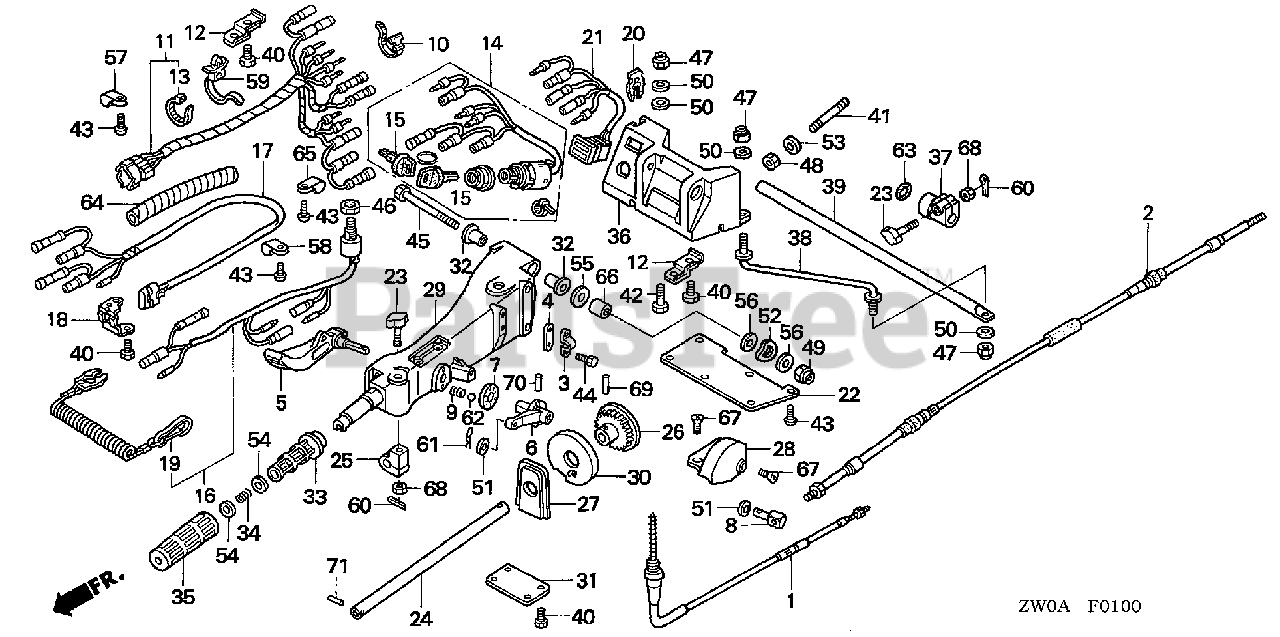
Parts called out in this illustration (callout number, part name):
1	CABLE, THROTTLE
2	CABLE, SHIFT
3	HOLDER, SHIFT CABLE
4	PLATE, SHIFT CABLE
5	LEVER, SHIFT
6	LINK, SHIFT (A)
7	PLATE, CLICK BASE
8	PIVOT, SHIFT
9	SPRING, CLICK
10	BAND B1, WIRE
11	HARNESS ASSY., CONTROL PANEL
12	STAY C, ENGINE WIRE HARNESS
13	TIE, CABLE (NATURAL 2.4X92)
14	SWITCH ASSY., COMBINATION
15	KEY ASSY., COMBINATION SWITCH
16	SWITCH ASSY., EMERGENCY STOP
17	SWITCH ASSY., POWER TRIM-TILT
18	STAY, POWER TILT SWITCH
19	WIRE, EMERGENCY
20	CLIP, EMERGENCY LOCK
21	LAMP ASSY., INDICATION (2-LED)
22	COVER, STEERING BRACKET
23	BOLT, FRICTION
24	PIPE, THROTTLE
25	BLOCK, THROTTLE FRICTION
26	GEAR, THROTTLE REEL
27	BRACKET, THROTTLE REEL (A)
28	COVER, SHIFT LINK
29	HANDLEBAR *NH282MU* (OYSTER SILVER METALLIC-U)
30	CAP, CABLE HOLDER
31	PLATE, REEL SETTING
32	BUSH, HANDLEBAR
33	PIPE, GRIP
34	SPRING, GRIP PIPE
35	RUBBER, GRIP
36	BRACKET, STEERING *NH282MU* (OYSTER SILVER METALLIC-U)
37	BLOCK, STEERING FRICTION
38	ROD, STEERING FRICTION
39	SHAFT, STEERING FRICTION
40	BOLT, HEX. (6X12)
41	BOLT, STUD (10X28)
42	BOLT, HEX. (8X32)
43	SCREW, PAN (5X12)
44	BOLT, HEX. (6X16)
45	BOLT, HEX. (12X100)
46	NUT, HEX. (16MM)
47	NUT, SELF-LOCK (8MM)
48	NUT, SELF-LOCK (10MM)
49	NUT, SELF-LOCK (12MM)
50	WASHER, PLAIN (8MM)
51	WASHER, PLAIN (6MM)
52	WASHER, WAVE (14MM)
53	WASHER (10MM)
54	WASHER (10MM)
55	WASHER, PLAIN (12MM)
56	WASHER, PLAIN (12MM)
57	CLIP (10.7MM)
58	CLIP (7.5MM)
59	STRAP, CABLE (105MM) (BLACK)
60	PIN, SPLIT (2.0)
61	PIN, LOCK SPECIAL (6MM)
62	BALL, CLICK
63	O-RING (15.54X2.26)
64	TUBE, SPIRAL (9X110)
65	CLIP, WIRE HARNESS (6.3MM)
66	COLLAR, DISTANCE (12.2X22X21.5)
67	SCREW, OVAL (6X16)
68	NUT, HEX. (6MM)
69	PIN, SPRING (3X20)
70	PIN, SPRING (4X20)
71	PIN, SPRING (4X28)
